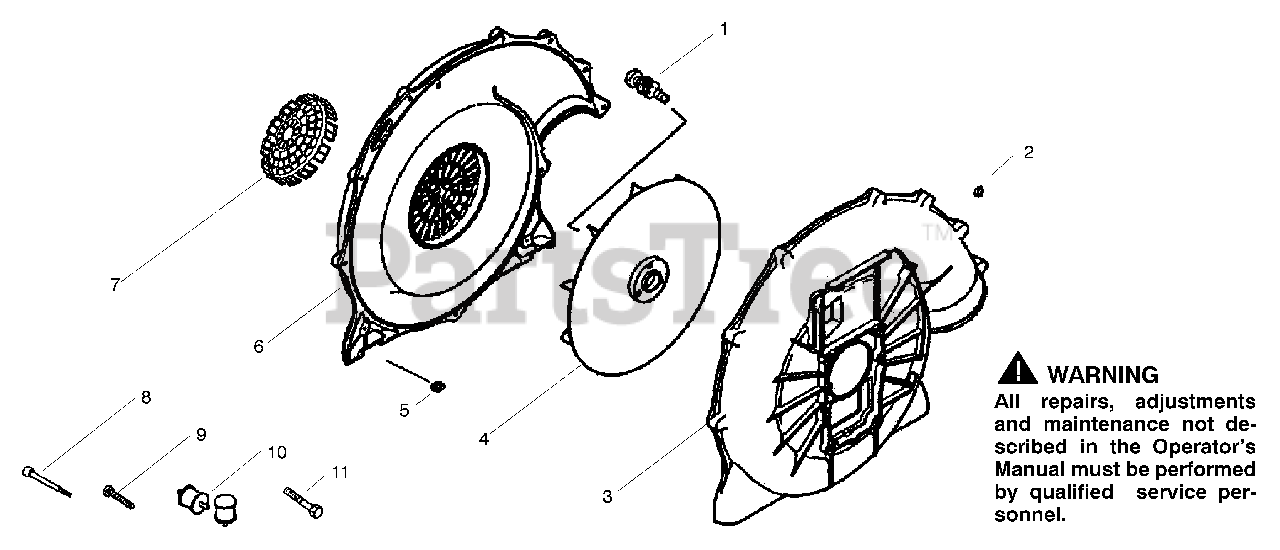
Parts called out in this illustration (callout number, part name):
1	Bolt-Lock
2	Nut-Nylon
3	Case-Fan
6	Case-Fan
7	Cover-Fan
8	Screw-Socket
9	Screw-Tapping m5x20
10	Isolator-Vibro Rubber
11	Bolt-Lock
